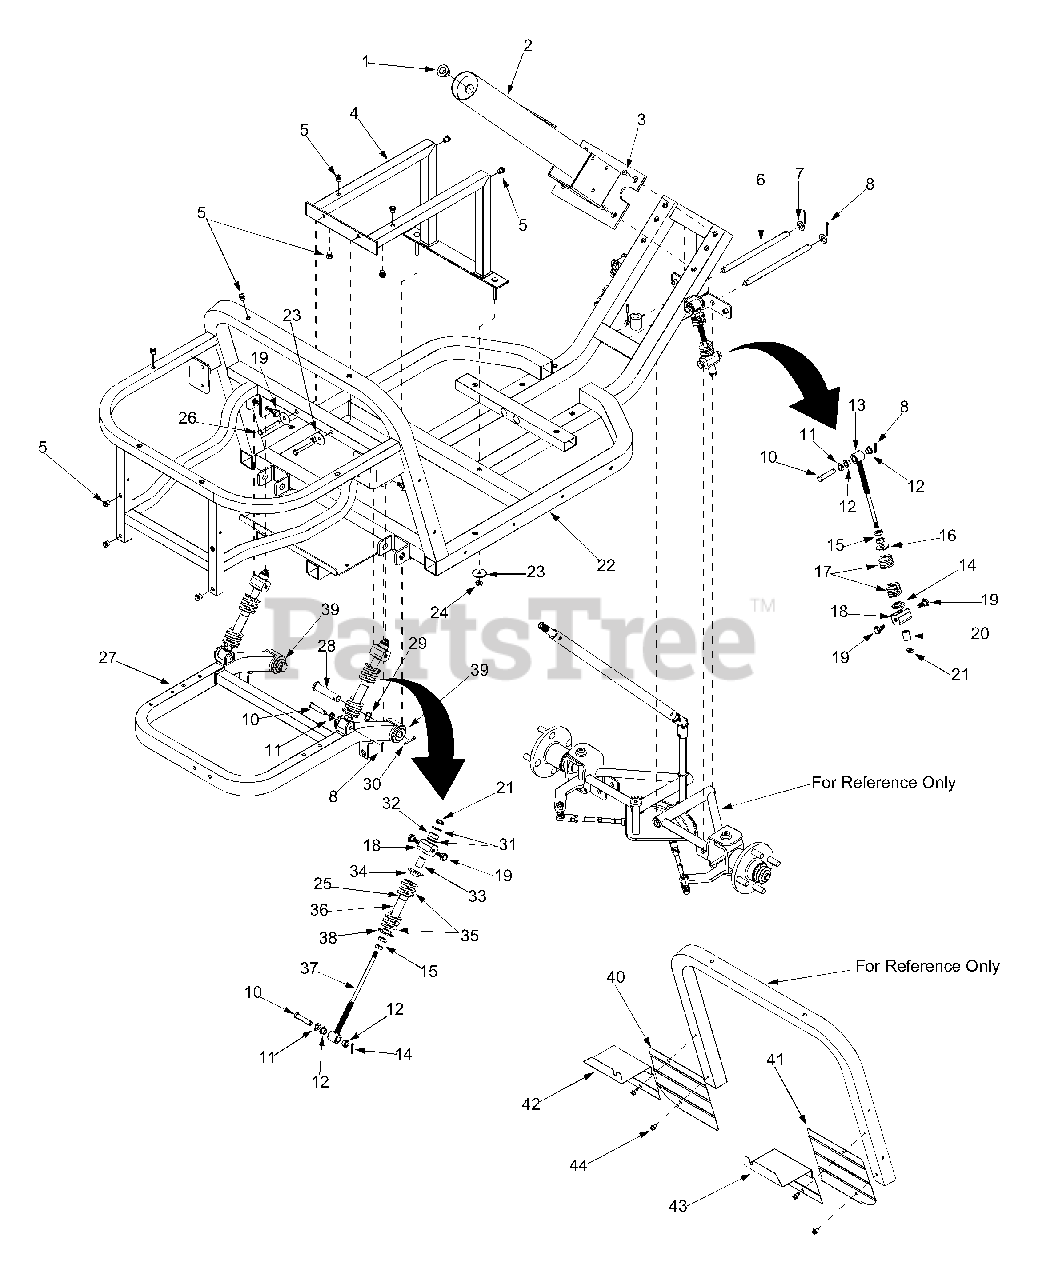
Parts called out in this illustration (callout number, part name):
1	Flange Bearing .63 ID x .62 Lg
2	Steering Column Assembly
3	Cap Screw 1/4-20 x .750
4	Seat Plate Mounting Assembly
5	Inset Screw 1/4-20
6	Pivot Shift Arm
7	Flat Washer .53 ID x .93 OD
8	Cotter Pin
10	Clevis Pin
11	Bowed Washer
12	Flange Bearing .376 ID x .502 OD
13	Bearing Rod Assembly
14	Shoulder Spacer .316 ID x .290 OD
15	Jam Nut 7/16-20
16	Shoulder Spacer .44 ID x .290 Lg
17	Compression Spring
18	Pivot Guide Assembly
19	Shoulder Screw .437 ID x .265 Lg
20	Spacer .341 ID x .560 OD
21	Flange Lock Nut 5/16-18
22	Main Frame Assembly
23	Flat Washer .285 ID x 1.25 OD
24	Hex Flange Nut 1/4-20
25	Rubber Bumper
26	Hex Cap Screw 1/4-20 x 2.25
27	Trailing Arm Frame Assembly
28	Clevis Pin
29	Spring Washer .625 ID x .885 OD
30	Cotter Pin
31	Washer .349 ID x .879 OD
32	Rubber Washer
33	Spacer .325 ID x .625 OD
34	Shoulder Spacer .316 ID x .350 Lg
35	Compression Spring
36	Spacer .438 ID x .750 OD
37	Bearing Rod Assembly
38	Shoulder Spacer .44 ID x .350 Lg
39	Flg Bearing .627 ID x .816 OD x .75
40	Upper LH Mudflap
41	Upper RH Mudflap
42	Lower LH Mudflap
43	Lower RH Mudflap
44	Hex Washer Screw 1/4-20 x .500
